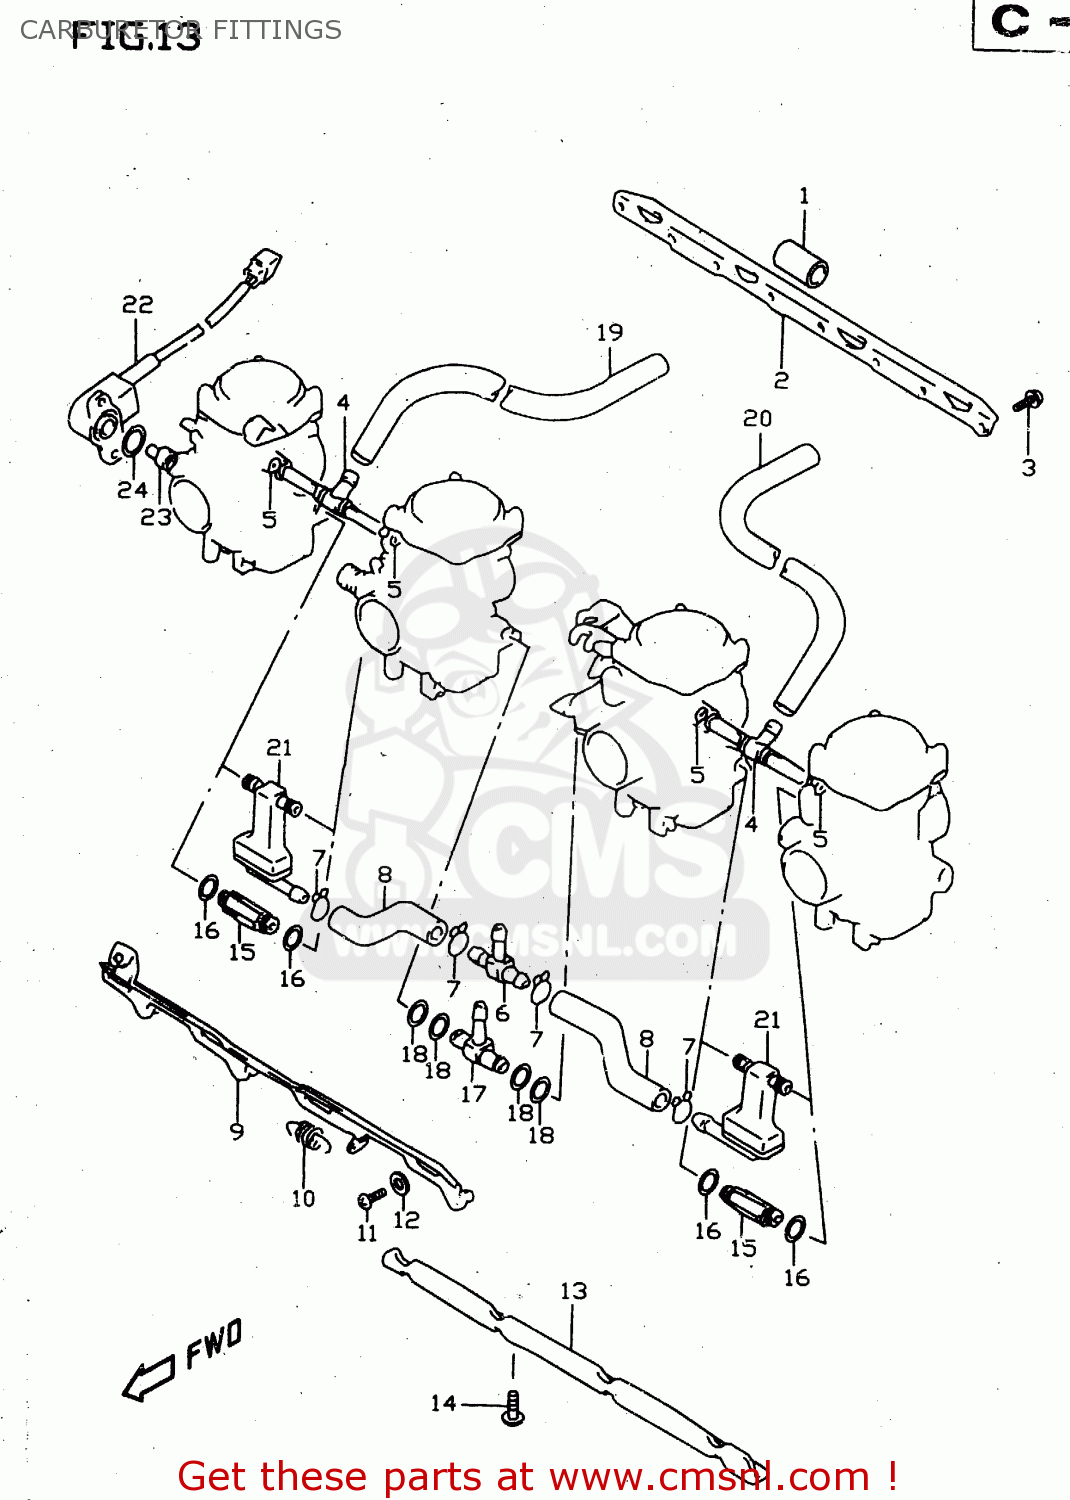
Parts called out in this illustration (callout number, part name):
1	PIPE
2	STAY,PLATE
3	SCREW
4	JOINT
5	O RING
6	JOINT
7	CLAMP
8	HOSE
9	LEVER,STARTER
10	SPRING
11	SCREW
12	WASHER
13	STAY,PLATE
14	SCREW
15	JOINT
16	O RING
17	JOINT
18	O RING
19	HOSE(7X11X600)
20	HOSE(7X11X600)
21	JOINT SET
22	SENSOR,THROTTLE
23	COLLAR
24	O RING
